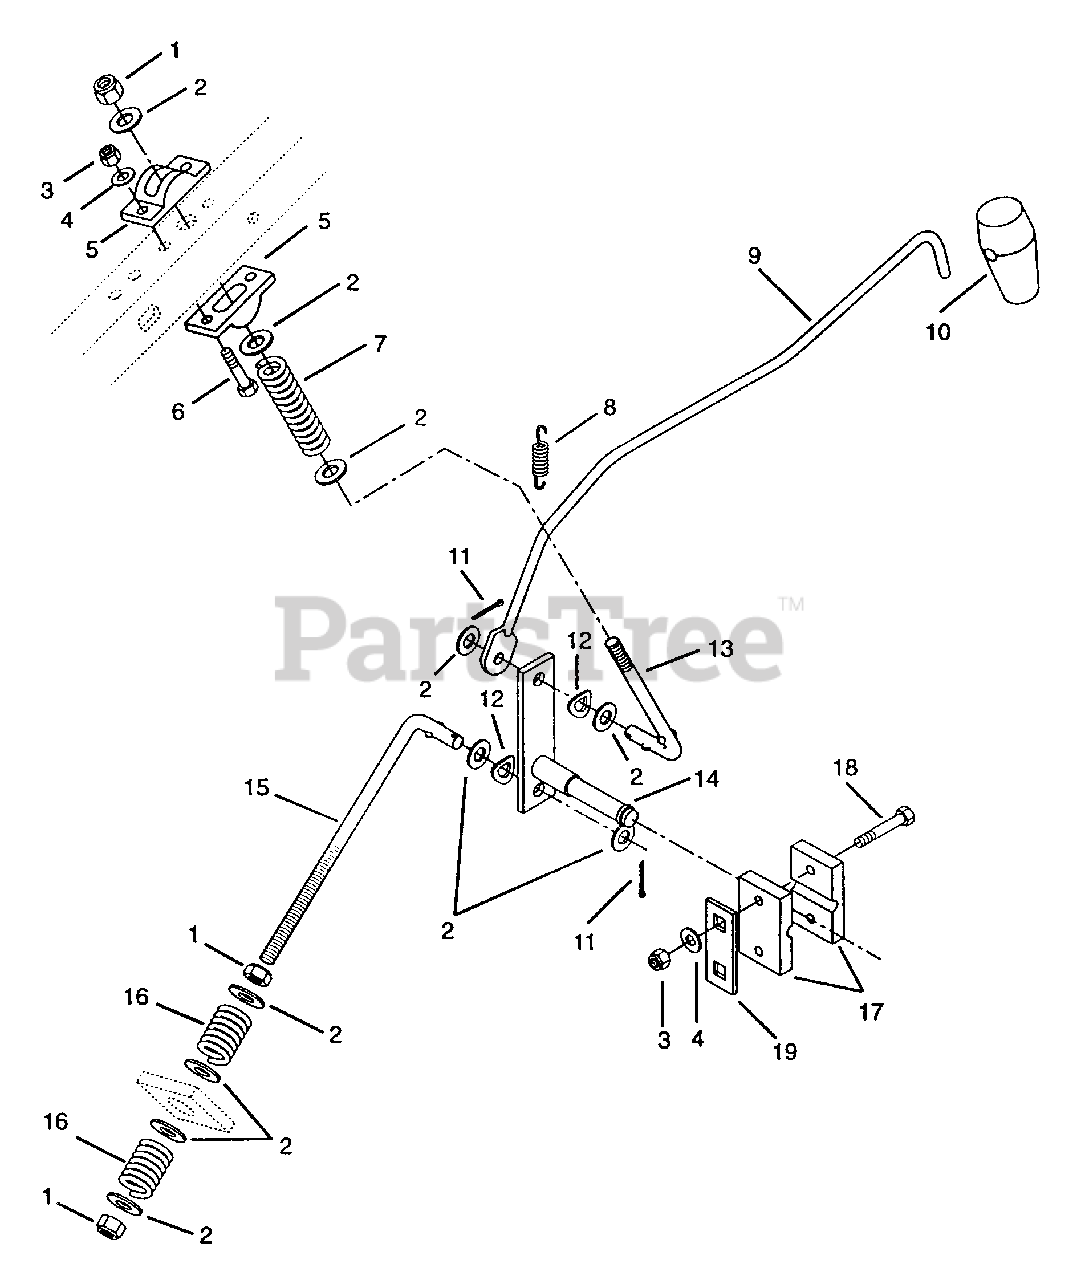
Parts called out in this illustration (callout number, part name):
1	Nut-Locking-Nylon .375-16 Grade 2
2	Washer-Flat-Steel .406 x .812 x .065
3	Nut-Locking-Nylon .250-20 Grade 2
4	Washer-Flat-Steel .281 x .620 x .065
5	Cam, Shifter
6	Bolt-Hex .25-20 x 1.00 Grade 5
7	Spring-Compression .081 x .720 x 2.75
8	Spring-Tension .041 x 1.25 x .50
9	Rod, Shifter
10	Handle, Rubber Shifter
11	Pin-Cotter .12 x .75
12	Spring Washer
13	Link, Shifter Stop
14	Weldment, Shifter Crank
15	Link, Shifter
16	Spring-Compression .125 x .78 x 1.00
17	Block, Shift Lever
18	Bolt-Hex .25-20 x 1.50 Grade 5
19	Shim, Mower Height Adjuster Bracket
